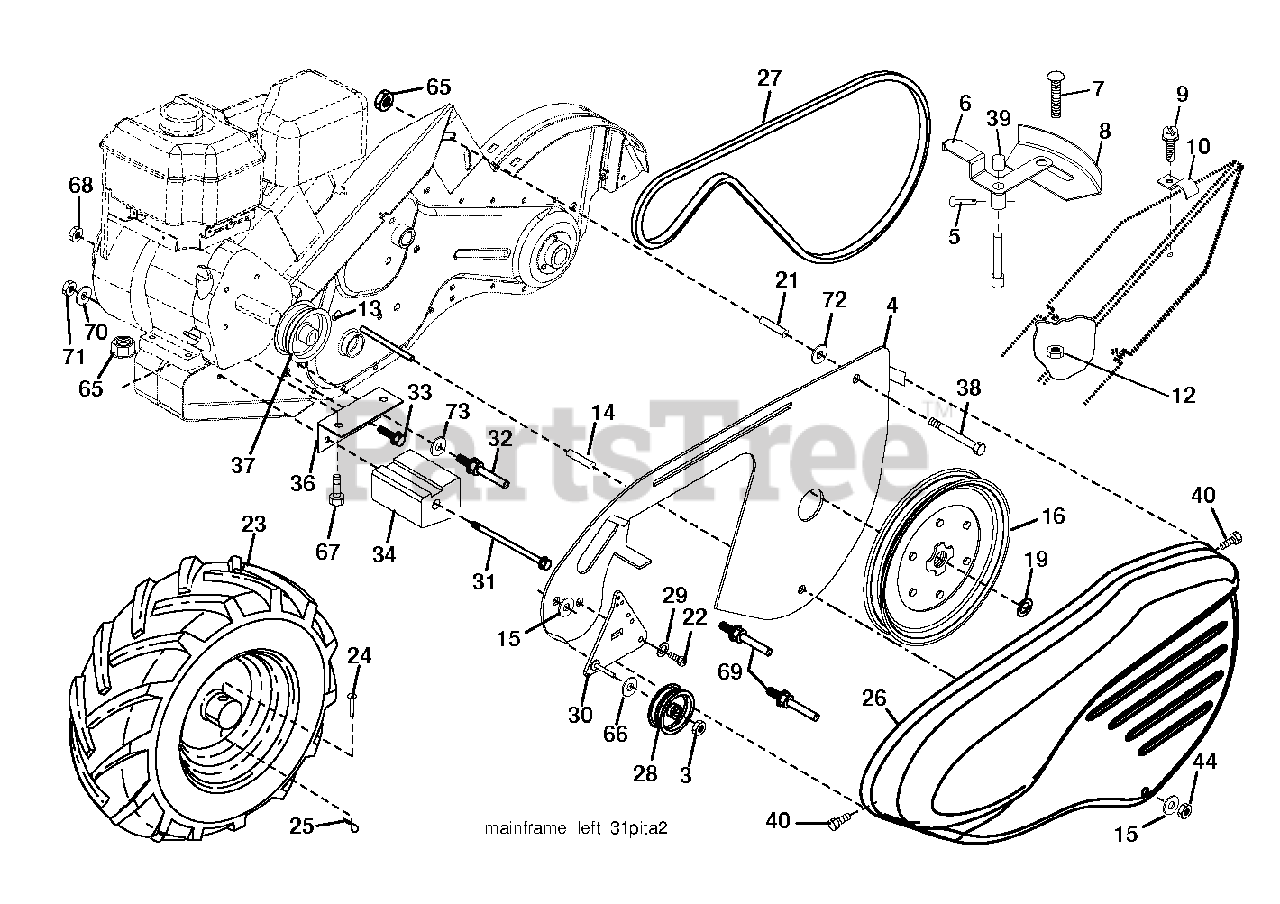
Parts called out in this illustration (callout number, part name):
3	LOCKNUT
4	SHIELD.INNER.BELT.GUARD.RT.BLA
5	PIN.SPIROL.FLARED
6	LEVER.ASM.SHIFT.RED
8	PANEL.INDICATOR.SHIFT.BLACK.
9	TAPPING SCREW
10	CLIP.PLATED
12	NUT
14	SPACER-SPLIT.327 X .42
15	WASHER.FLAT.34X1.38X22
16	SHEAVE, TRANSMISSION
19	RETAINING RING LT
21	SPACER SPLIT
23	WHEEL.ASM.DRT.13X5-6.LT.SILVER
24	RIVET
25	RETAINER M
26	GUARD.BELT.TILLER.ORANGE
27	V-BELT
28	PULLEY-IDLER TI
30	BRACKET.IDLER.ASM.LONG
31	BOLT.FIN.HEX.3/8-16UNC X 11.5
32	SHIFT ARM CRT
33	BOLT
34	COUNTERWEIGHT.LH
36	BRACKET.REINFORCEMENT.LH.PNT
37	ENGINE PULLEY
38	BOLT
39	CAP.PLUNGER.BLACK
40	SCREW.HEX.WSH.SLT.#10-24X.50
44	NUT.71038.31-18.HEX.NYLOCK
65	LOCKNUT-FLANGE 5/16-18
66	WASHER
67	BOLT, HEX 5/16-18X1-3/4
69	KEEPER.BELT.ENGINE
70	WASHER
72	SPACER (2 2MC)
73	WASHER
